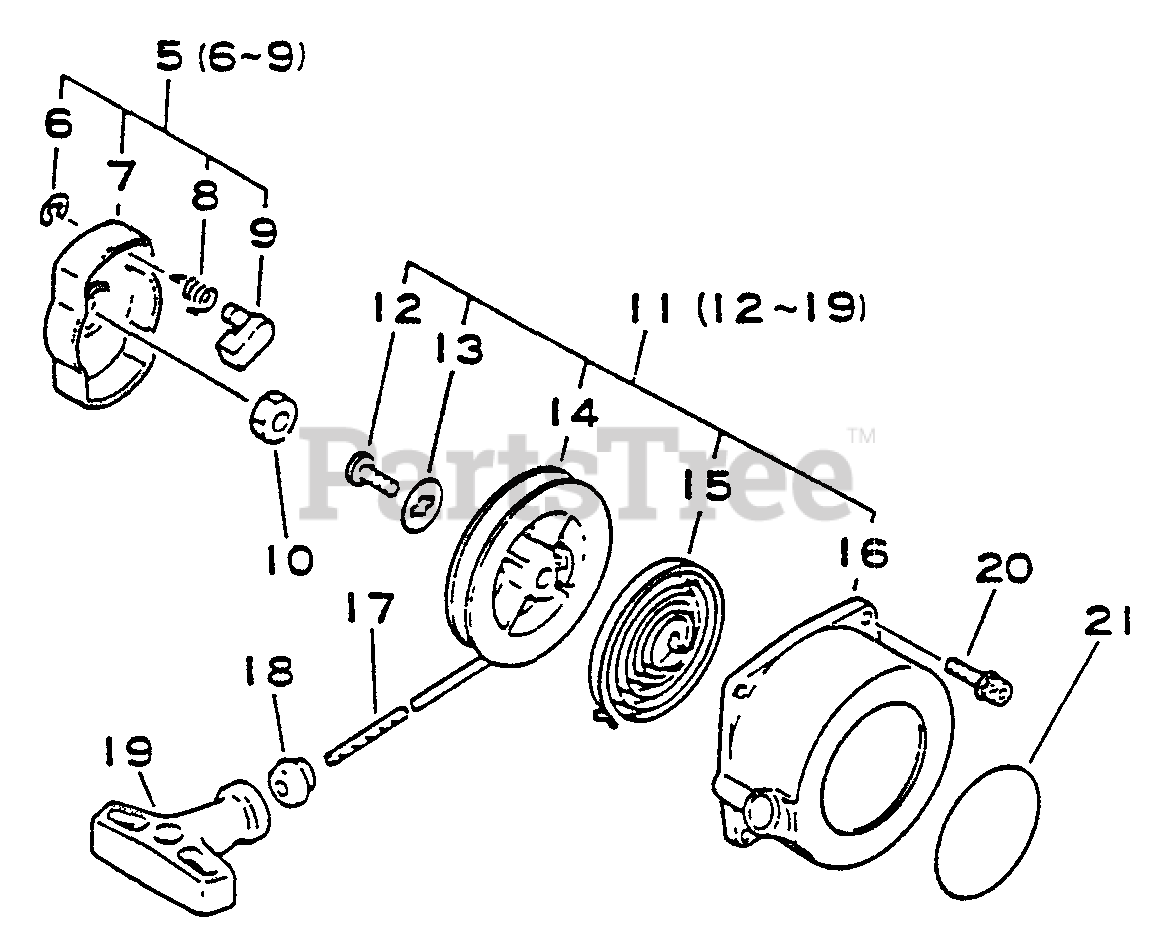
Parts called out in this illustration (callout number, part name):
5	PAWL ASSY, STARTER
6	RING, RETAINING - 6
7	PAWL CATCHER
8	SPRING, RETURN
9	PAWL, STARTER
10	NUT 8×1.25
11	STARTER ASSY
14	REEL, ROPE
15	SPRING, RECOIL
16	CASE, STARTER - ORANGE
17	ROPE, STARTER 4.0×880
18	GUIDE, ROPE
19	GRIP, STARTER
20	BOLT 4×20
21	LABEL - ECHO
